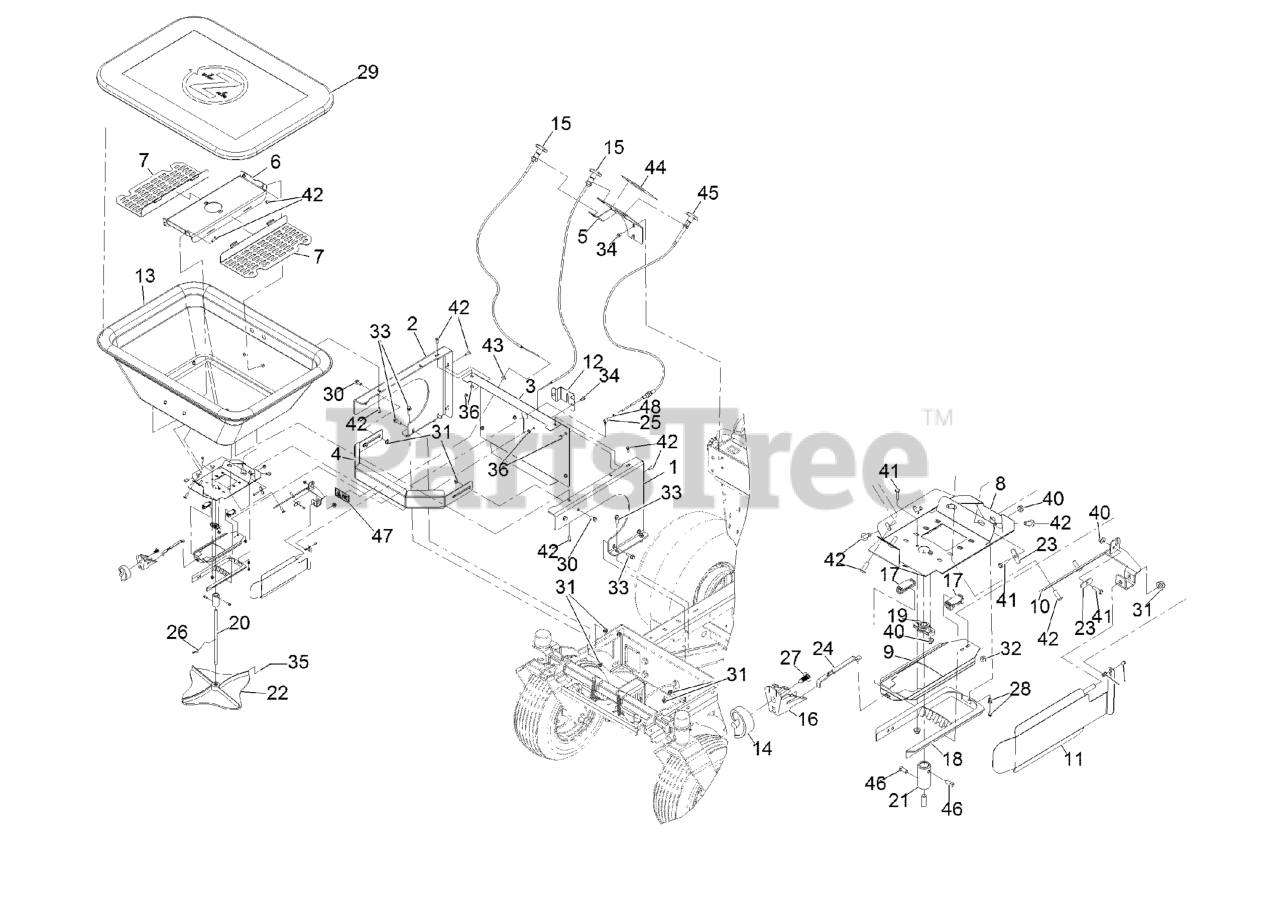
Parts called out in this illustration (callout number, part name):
1	Side-Hopper, Rt
2	Side-Hopper, Lt
3	Backshield-Hopper
4	BUMPER-FRONT, HOPPER
5	Mount-Speedometer
6	Pan-Hopper, 150
7	Screen-Hopper, 150
8	Plate-Base, Hopper
9	Door-Slide, Hopper
10	Mount-Deflector, Side
11	Deflector-Side, Spreader
12	Bracket-Hopper, 150 Cable Offset
13	Hopper-150Lb
14	DIAL
15	CABLE-PUSH/PULL
16	MOUNT-DIAL
17	GUIDE-RATE, GATE
18	DIFFUSER
19	BEARING-FLANGE
20	Shaft-Hopper, 150
21	COUPLER-SS
22	SPINNER-SPREADER
23	RETAINER, CABLE
24	LINKAGE-GATE, RATE
25	BALL JOINT-SS
26	WIRE-AGITATOR
27	CLIP
28	RETAINER-CABLE, WIRE
29	COVER-HOPPER, LARGE
30	SCREW-HHF
31	Nut-Hex Flange
32	Nut,NYL Lock,#10-32,ST/ST 18-8
33	SCREW-HHF
34	SCREW-HHF
35	PIN-COTTER
36	Nut-Hex Flange
40	Nut-Hex Flange
41	SCREW-HH
42	Screw-Hsbhf
43	Grommet-Rubber
44	DECAL-HOPPER CONTROL
45	CABLE-PUSH/PULL
46	Screw-SQH
47	Decal-Dismemberment Hazard
48	Nut,Hex Jam Mch Scr,10-32,Sst
